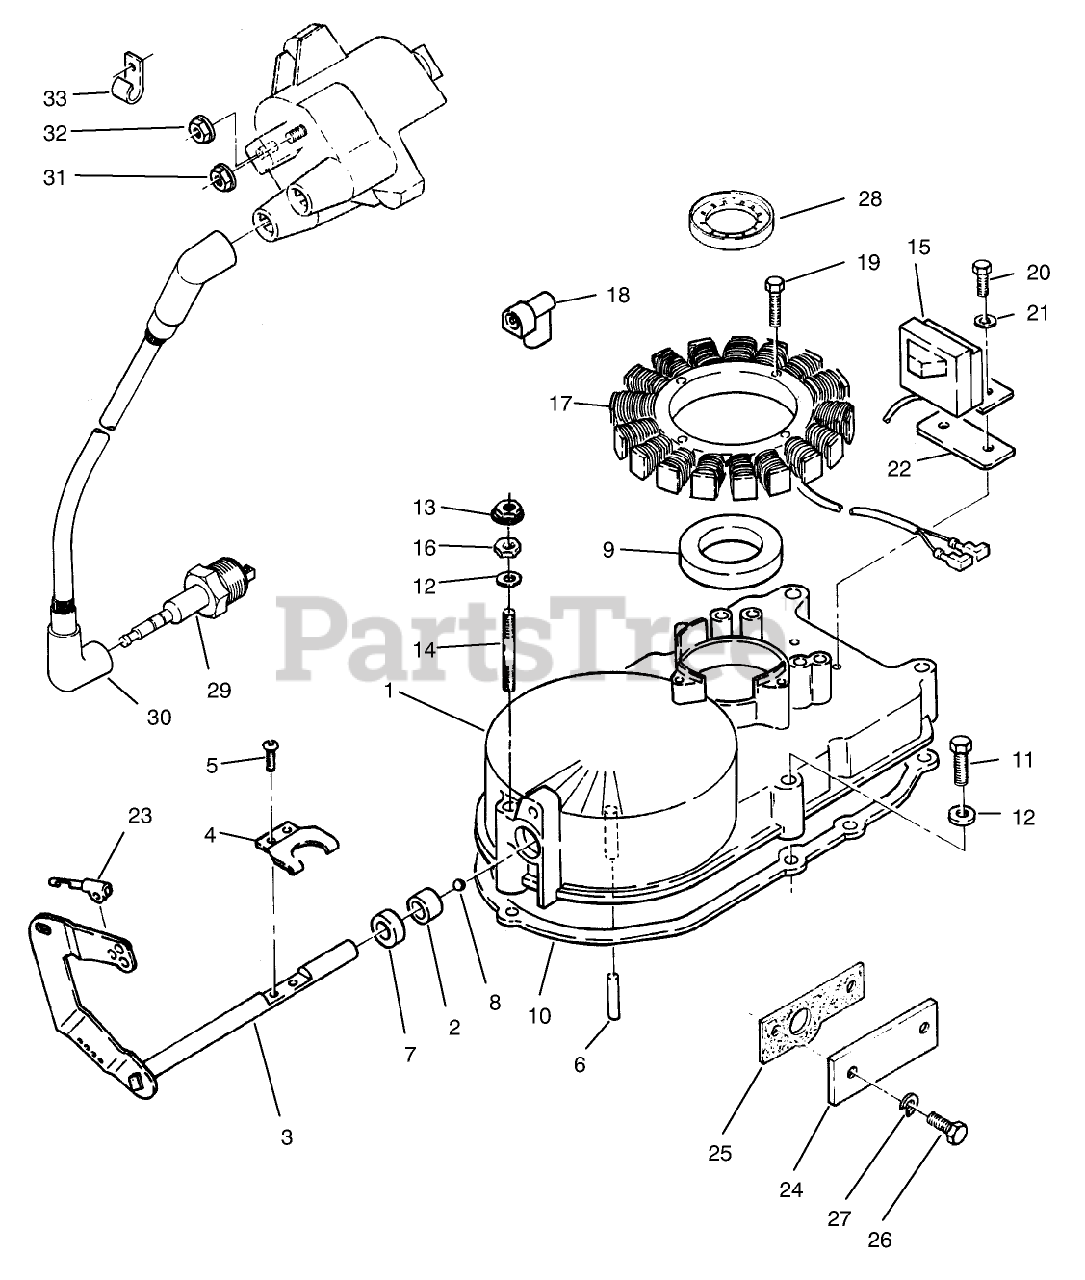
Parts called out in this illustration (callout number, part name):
1	GEAR-CASE KIT
5	SCREW-PAN HD
12	WASHER
16	NUT-GEAR COVER
25	GASKET
29	SPARK PLUG
